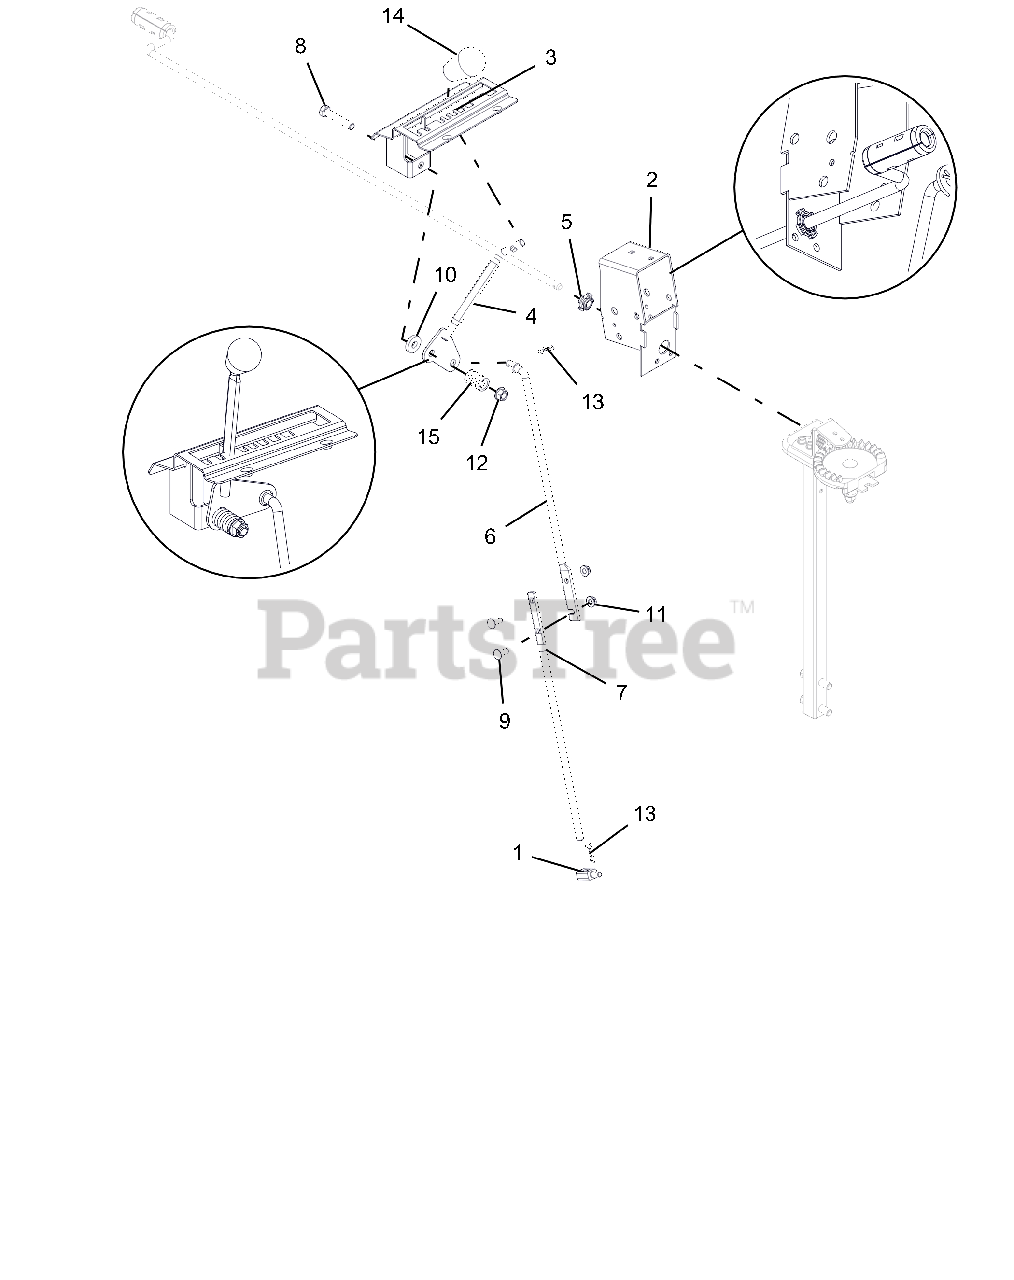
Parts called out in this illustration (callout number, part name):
1	PIVOT,SHIFT ROD .375-16(TRUNN)
2	WELDMENT, BRACKET INTERLOCK
3	WELDMENT, DETENT PLATE-COMPACT
4	LEVER, CONTROL-SHIFT(WELDMENT)
5	CRANK BUSHING, NYLON CHUTE BK
6	ROD, SHIFT - UPPER
7	ROD, SHIFT - LOWER
8	@BLT-HEX .38-16X2.00 GR5 YWZC
9	@BLT-RDHDSQNK .25-20X.75 G5YZ
10	WSHR-FL-STL .406X1.00X.188 YWZ
11	@NUT-LK-CTR-FLG .25-20 YWZC
12	@NUT-LK-TOP-FLG .38-16 YWZC
13	PIN-HAIR INT .08X.18X1.18 YWZC
14	KNOB,SOFT TEARDROP,PUSH-ON GRY
15	SG-COMP .125X.781X1.250
